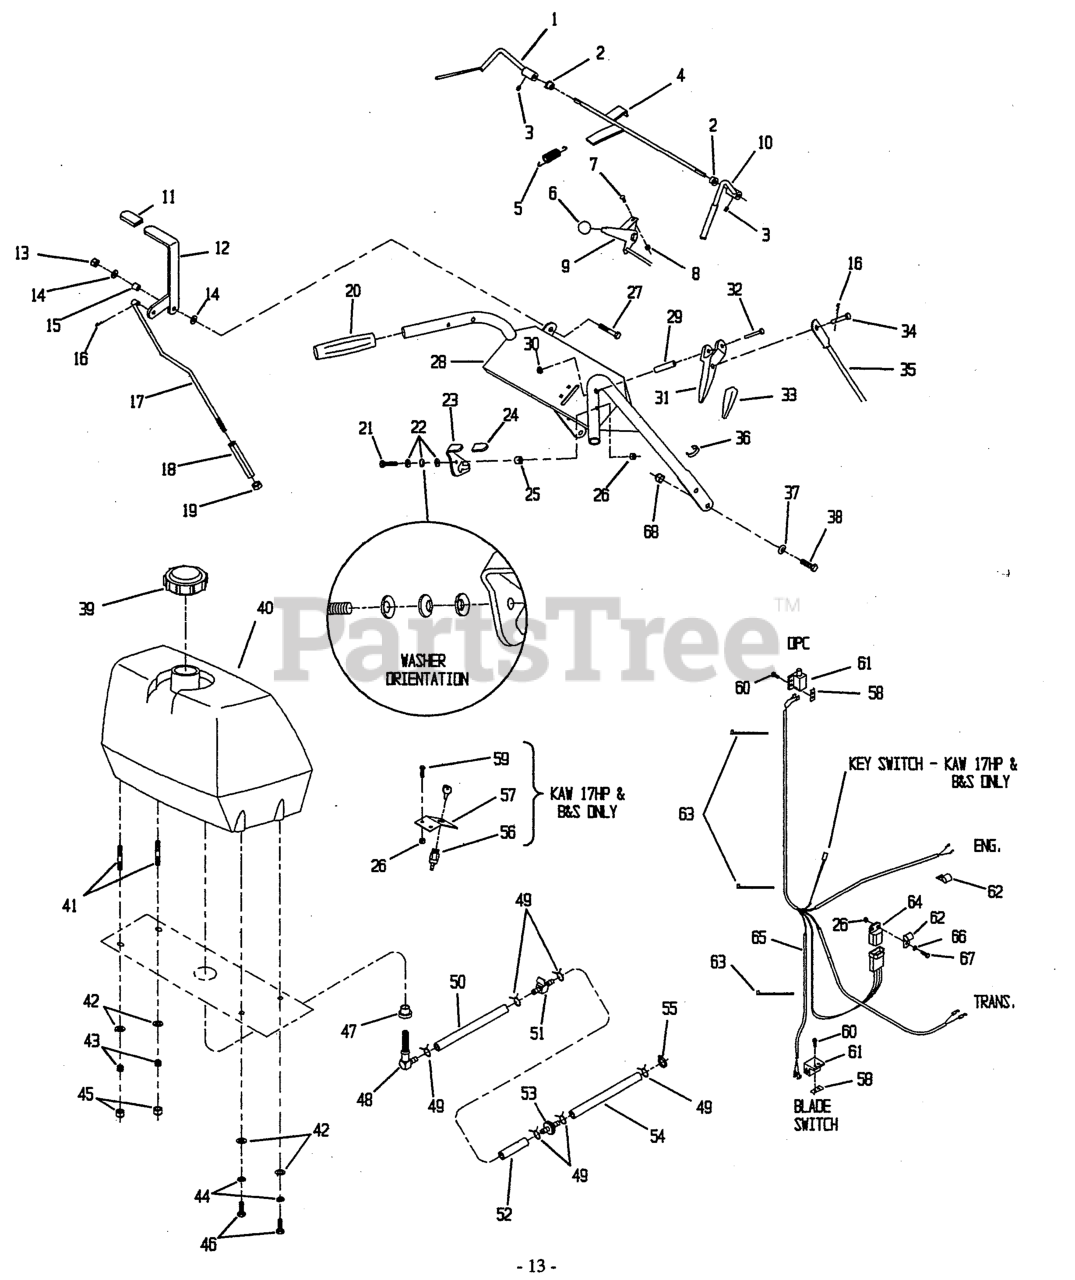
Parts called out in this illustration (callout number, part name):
1	Lever, Wldmt Opc Lh
2	Bushing, Nylon
3	Screw, Set 312-24x.312
4	Rod Weldmt, Opc
5	Spring, Actuator
6	Knob, Ball Red
7	Bolt, Carriage #10-24x1/2 G2
8	Nut, Nyloc #10-24
9	SCREW-CARR
10	Lever, Wldmt Opc Rh
11	Grip, Lever
12	Clutch Lever W/Grip
13	Nut, Nyloc 3/8-16
14	Washer, Flat Std 3/8
15	Spacer
16	Pin, Hair Cotter .0585 #2
17	Linkage, Upper
18	Tumbuckle, 3/8-16 Ss
19	Nut, Reg Hex 3/8-16
20	Grip, Handle
21	Screw, Hex Cap 1/4-20x2 1/4
22	Washer, Disc Spring 1/4
23	Latch, Thumb Lh W/Grip
24	Grip, Latch
25	Spacer
26	Nut, Nyloc 1/4-20
27	Screw, Hex Cap 3/8-16x1-3/4
28	Handle Wldmt
29	Pin, Roll 5/16x1
30	Nut, Pal 3/16
31	Lever, Drive W/Grip
32	Pin, Clevis 3/16x1 3/4
33	Grip, Drive Lever
34	Pin, Clevis 5/16x1 7/8
35	Linkage, Drive Wheel
36	Clip, Cable
37	Washer, Disc Spring 3/8
38	Screw, Hex Cap 3/8-16x1
39	Cap, Fuel Tank
40	Tank, Fuel Intermediate
41	Stud
42	Washer, Flat SAE 5/16
43	Spring, Fuel Tank
44	Washer, Lock Hlcl Spg 5/16 Hvy
45	Nut, Nyloc 5/16-18
46	Screw, Hex Cap 5/16-18x3/4
47	Bushing, Fuel Valve
48	Elbow W/Screen
49	Clamp, Fuel Line
50	Hose, Fuel Line 6"
51	Valve, Fuel
52	Hose, Fuel Line 2.5"
53	Filter, Fuel
54	Hose, Fuel Line 12"
55	Clamp, Fuel Line
56	Switch, On/Off
57	Bracket, Key Switch
58	Plate, Tapped
59	Screw, Hex Cap 1/4-20x5/8
60	Screw, Mach Crph 10-24x5/8
61	Switch, Neutral Lockout
62	Clip, 3/8 Loom
63	Tie, Plastic
64	Module, Wiring Harness
65	Harness, Wiring
66	Washer, Flat Std 1/4
67	Screw, Hex Cap 1/4-20x3/4
68	Nut, Whizlock 3/8-16
